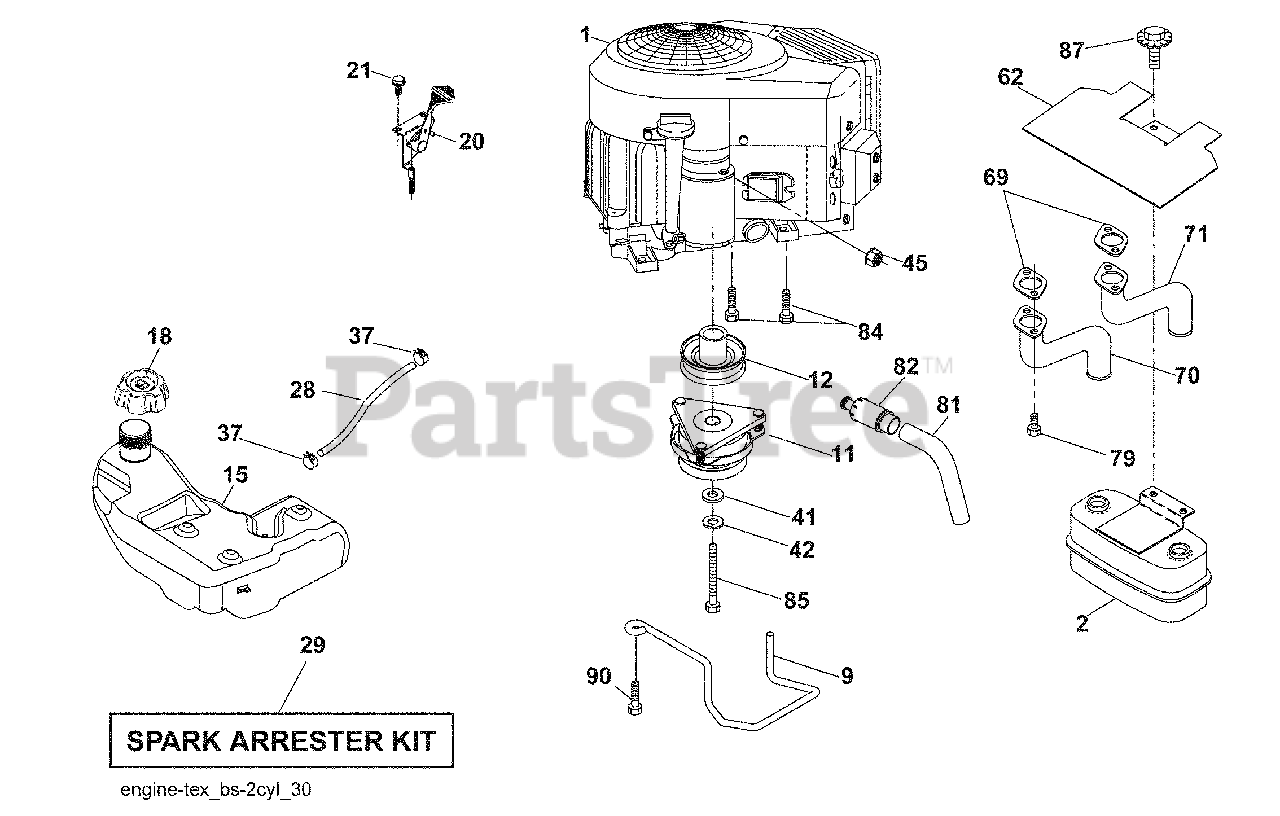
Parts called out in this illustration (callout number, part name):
11	Muffler
12	Keeper Belt Engine
15	Clutch Ogura
18	Pulley Engine
28	Control Throttle
29	Screw #10 x 0.750 BOS Thread
41	Spark Arrester Kit
42	Clamp Hose
45	Washer 1-1/2 OD x 15/32 ID x .250
62	Washer Lock 7/16
69	Nut Keps Hex 1/4-20 unc
70	Shield Heat Muffler
71	Exhaust Tube RH
79	Screw Socket Head 5/16-18 x 1
81	Tube Drain Oil Easy
82	Plug Drain Oil
84	Screw 3/8-16 x 1-1/4
85	Bolt 7/16-20 x 4
87	Bolt 5/16-18 x 3/4
90	Screw 3/8-16 x 1
